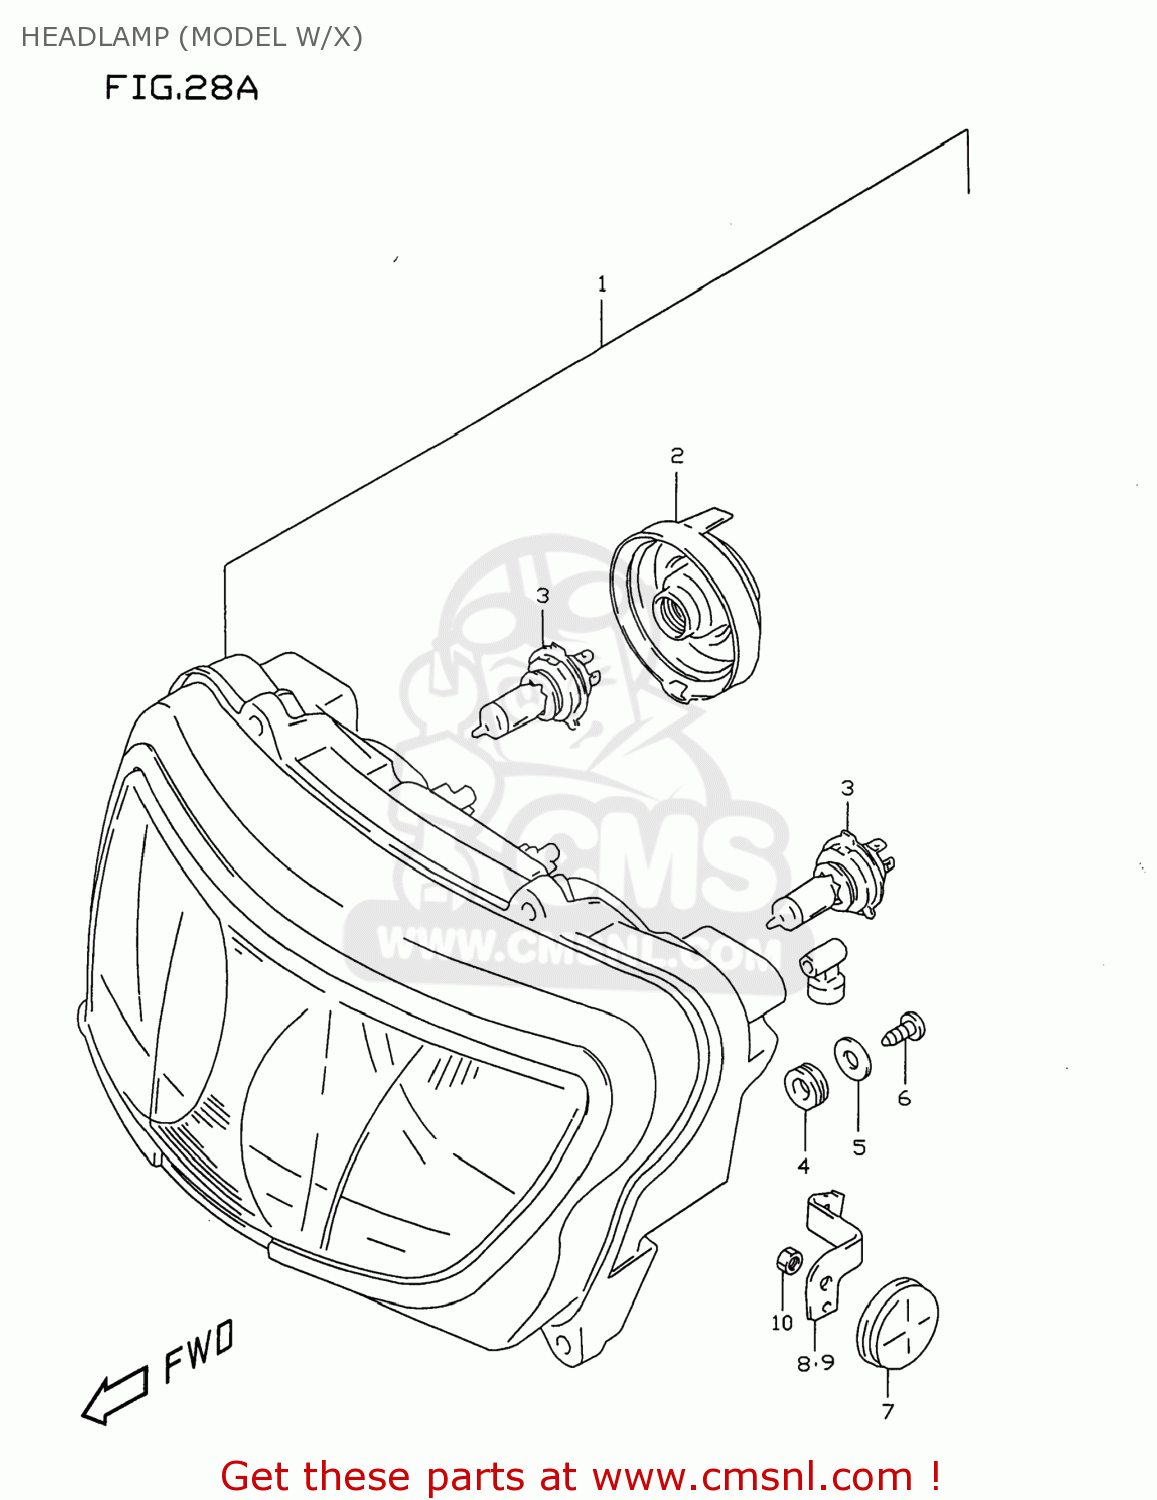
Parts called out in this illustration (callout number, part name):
1	HEADLAMP ASSY
2	COVER,SOCKET
3	BULB(12V60/55W,H4)
4	CUSHION,HEADLAMP
5	WASHER (5.5X18X1)
6	SCREW
7	REFLECTOR,REFLEX FR
8	BRACKET,FR SIDE RR,R
9	BRACKET,FR SIDE RR,L
10	NUT
